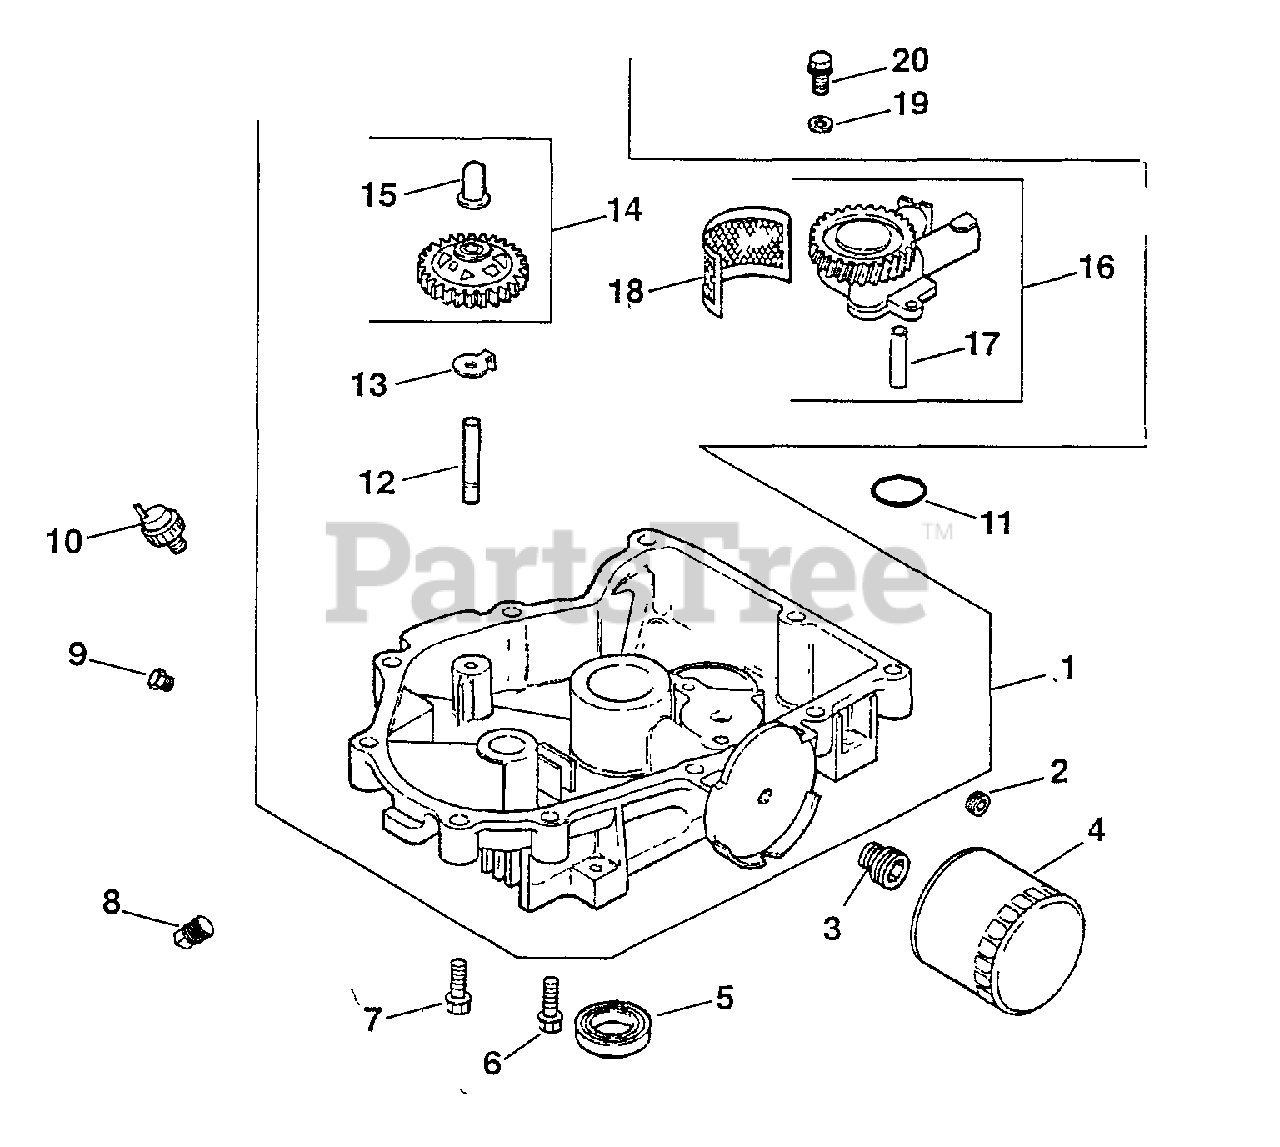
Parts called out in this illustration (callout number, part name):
1	PAN , OIL ASSEMBLY USE 24 199 32-S
2	PLUG, PIPE CTSK 3/8" USE 25 139 62-S
3	NIPPLE, OIL FILTER
4	OIL FILTER
5	SEAL, OIL (KM)-USE 25 032 06-S
6	SCREW, FLG M8X1.25X45
7	SCREW, HEX FLANGE -USE 24 086 17-S
8	PLUG, SQ HD PIPE 3/8" USE 25 139 57-S
10	SWITCH - USE 25 099 24
12	SHAFT, GOVERNOR GEAR
14	KIT, GOVERNOR GEAR W/PIN
15	PIN, GOVERNOR REGULATING
16	PUMP, OIL-DISCONTINUED
18	SCREEN, OIL-USE 24 162 26-S
19	WASHER - USE M-631005
20	SCREW - USE M-645025
